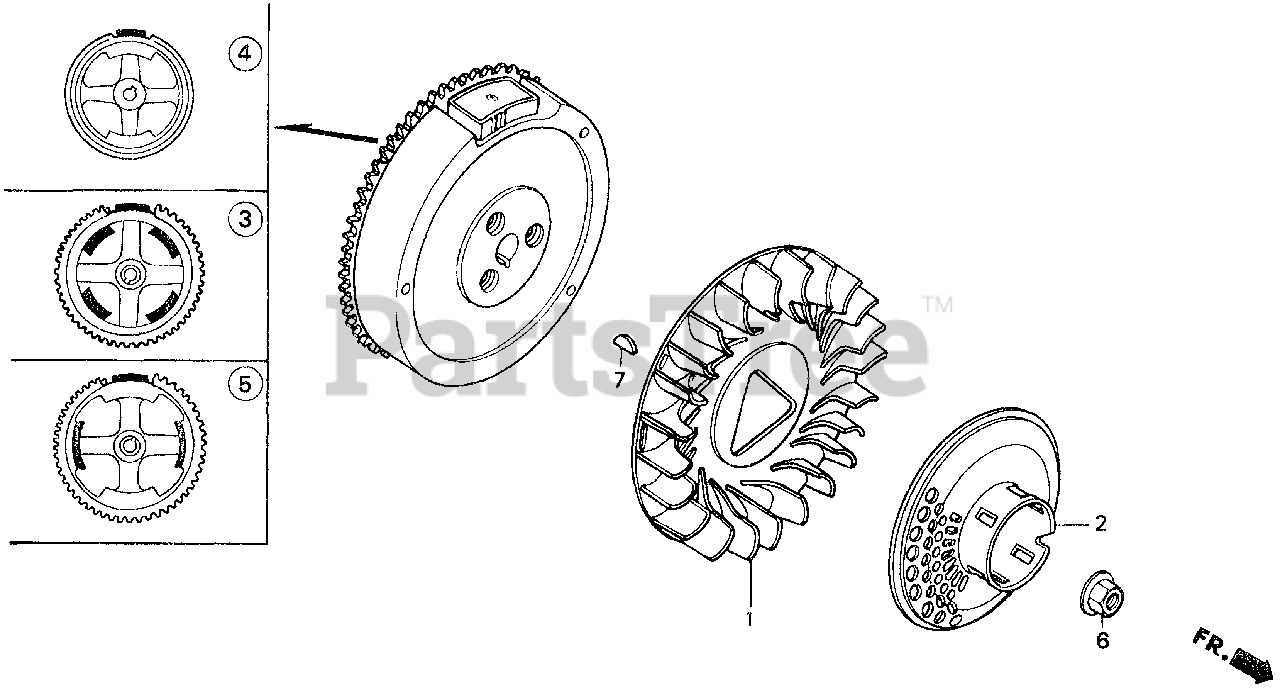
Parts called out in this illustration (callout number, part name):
1	FAN, COOLING
2	PULLEY, STARTER (SCREEN GRID)
3	FLYWHEEL (4 POLE)
6	NUT, SPECIAL (16MM) (1)
6	NUT, SPECIAL (16MM)
7	KEY, SPECIAL WOODRUFF (25X18)
